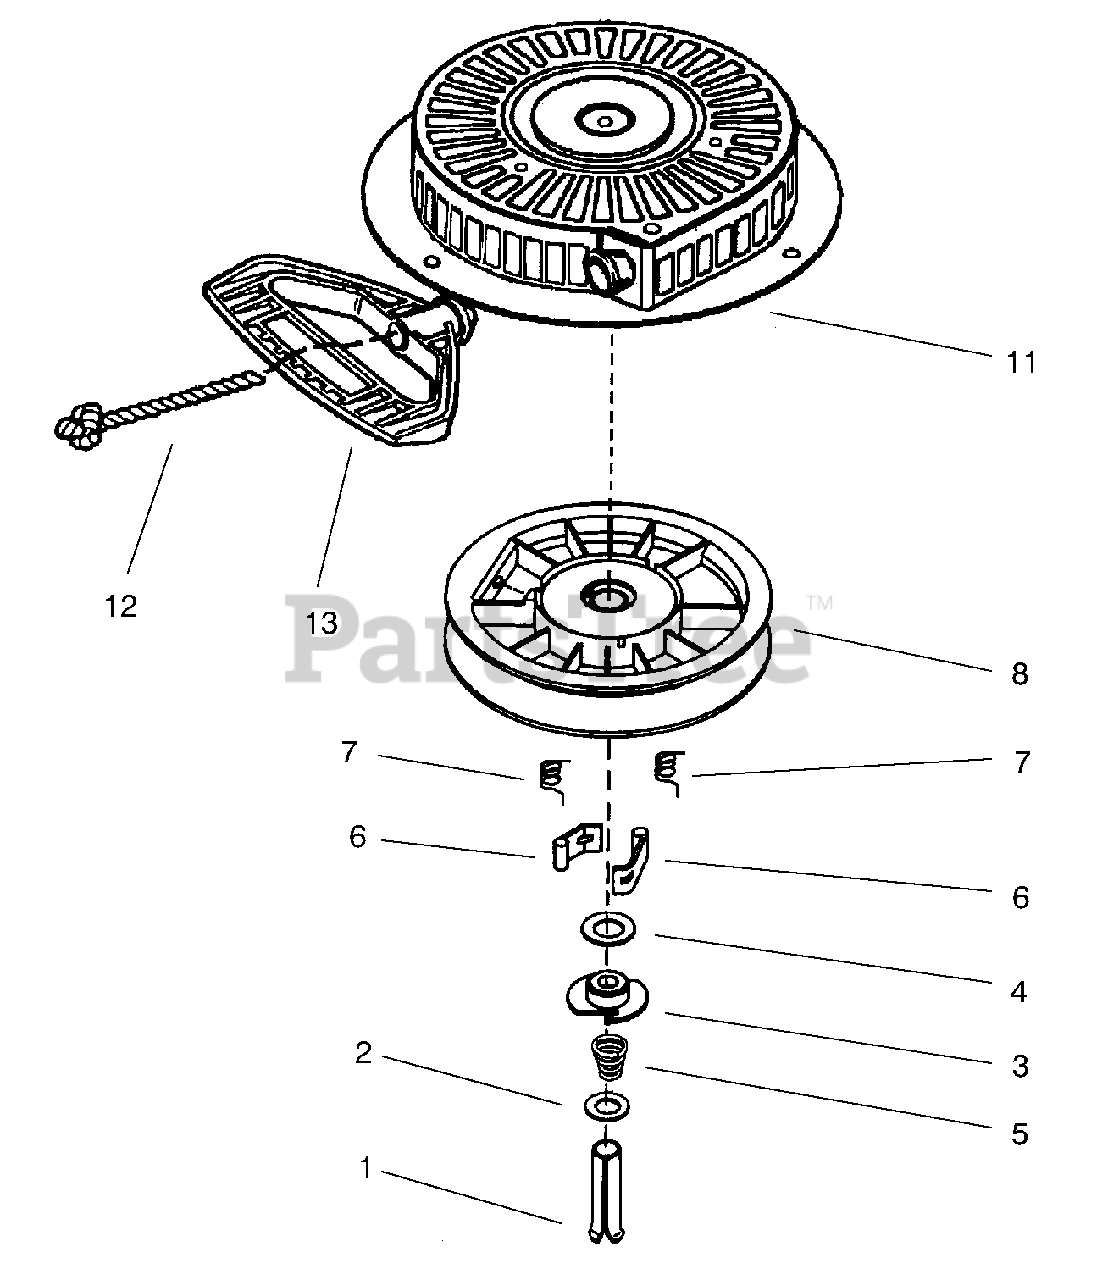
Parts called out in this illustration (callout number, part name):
1	Pin-Spring (Incl. Ref. #4)
2	Washer
3	Retainer
4	Washer
5	Spring-Brake
6	Dog-Starter
7	Spring-Dog
8	Pulley & RewindSpring Assembly
11	Starter Housing Asm
12	Rope-Starter
13	Handle-Mitten Grip
